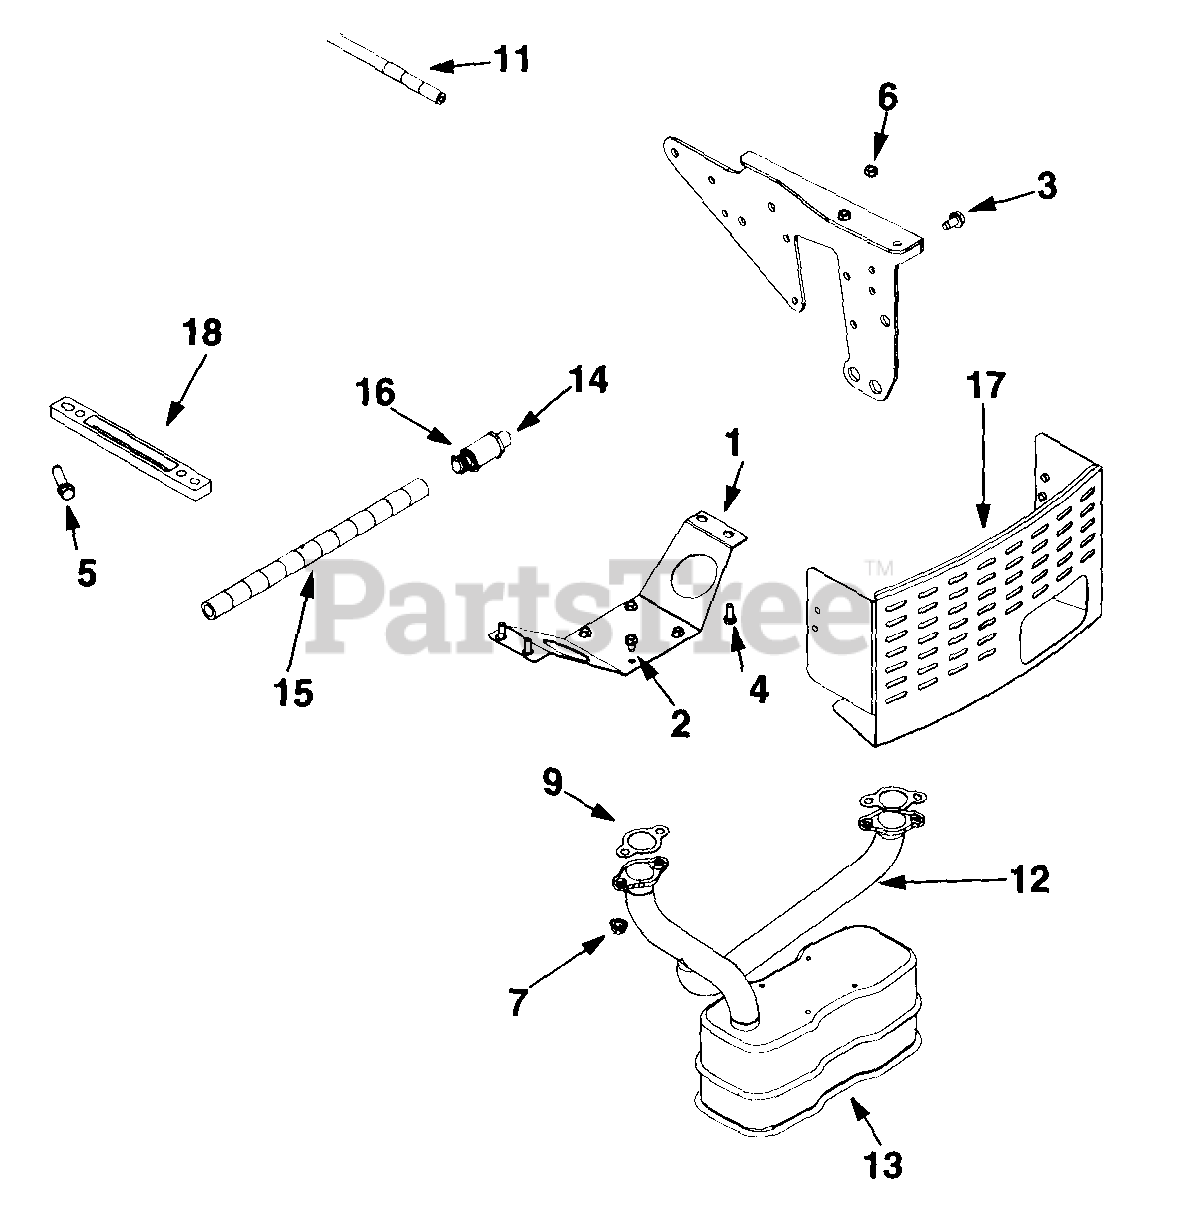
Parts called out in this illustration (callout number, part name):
1	Muffler Mounting Bracket
2	Hex Wash. Hd. Tap Scr. 1/4-20 x .5"
3	Hex Wash. Hd. Tap Scr. 5/16-18 x .62'
4	Hex Bolt 1/4-20 x .62" Lg.
5	Hex Wash. TT-Tap Scr. 3/8-16 x 1.5"
6	Hex Sems Nut 1/4-20 Thd.
7	Flange Nut
9	Exhaust Gasket
11	Fuel Line 60" Lg.
12	Exhaust Pipe
13	Muffler
14	Oil Drain
15	Oil Drain Extension Hose
16	Oil Drain Cap
